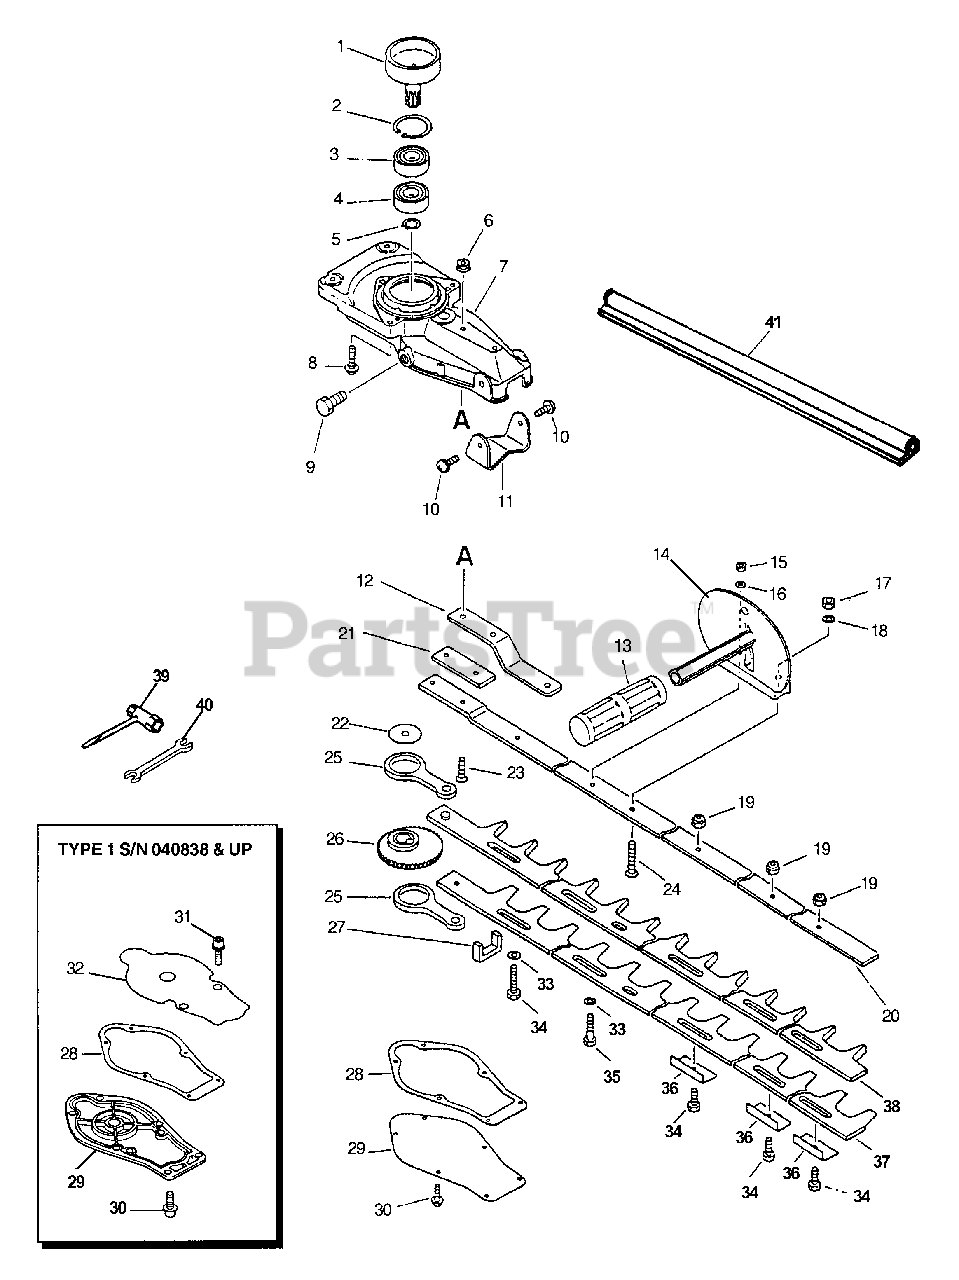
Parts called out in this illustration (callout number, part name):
1	DRUM, CLUTCH
2	E-RING 30
3	BEARING, BALL 6202
4	BEARING, BALL 6202
5	RING, SNAP 14
6	NUT, HEX M6
7	HOUSING, GEAR CASE
7	CASE, GEAR
8	SCREW 5×25
9	BOLT 8×8 SP
10	SCREW 5×10
11	STAND
12	PLATE, ANGLE
14	HANDLE, FRONT
16	WASHER 5.5×18×1
17	NUT, LOCK M5
18	WASHER 5.5×18×1
19	NUT, LOCK 6
20	BAR, FRAME
21	PLATE, EYE
23	SCREW 6×25
24	SCREW 5×30
25	ROD, CONNECTING
28	GASKET, GEAR CASE
29	COVER, GEAR CASE
30	BOLT 4×10
30	BOLT 4×12
31	BOLT 5×12
32	PLATE, GEAR CASE
33	WASHER 6.5×15.5×0.6
34	BOLT, CUTTER
35	BOLT 6×35
36	INSULATOR
37	BLADE - LOWER
38	BLADE - UPPER
39	T-WRENCH 13×19×180
40	SPANNER 8×10
41	SCABBARD
